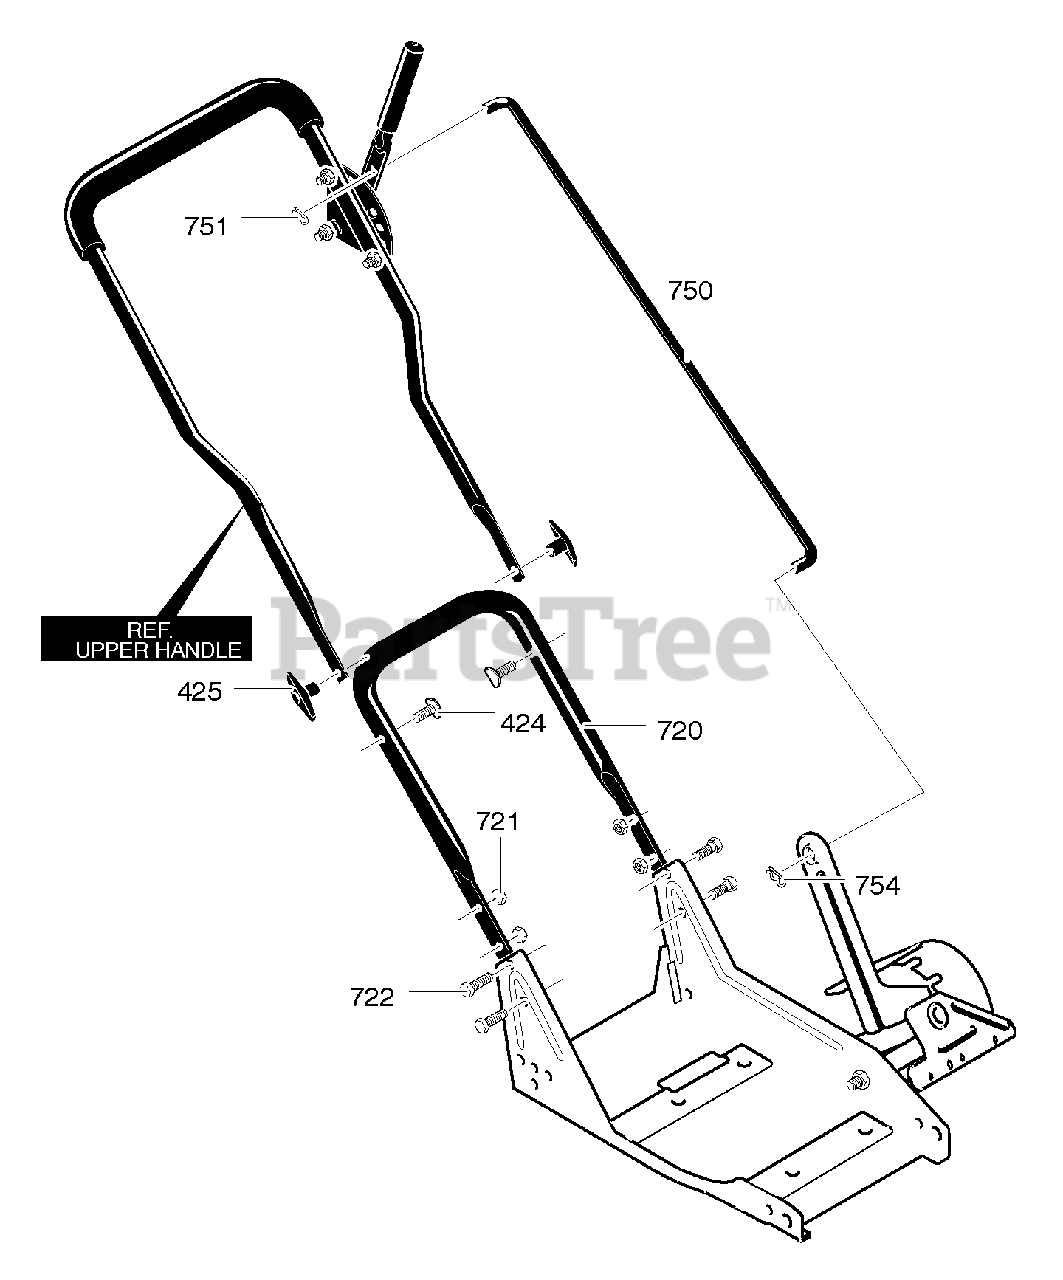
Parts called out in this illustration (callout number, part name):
424	Bolt, 5/16-18x1.75
425	Knob, Wing 5/16-18
720	Lower Handle
721	Nut, 5/16-18
722	Screw, 5/16-18 x 0.63
750	Control Rod
751	Hair Pin
754	Hair Pin
